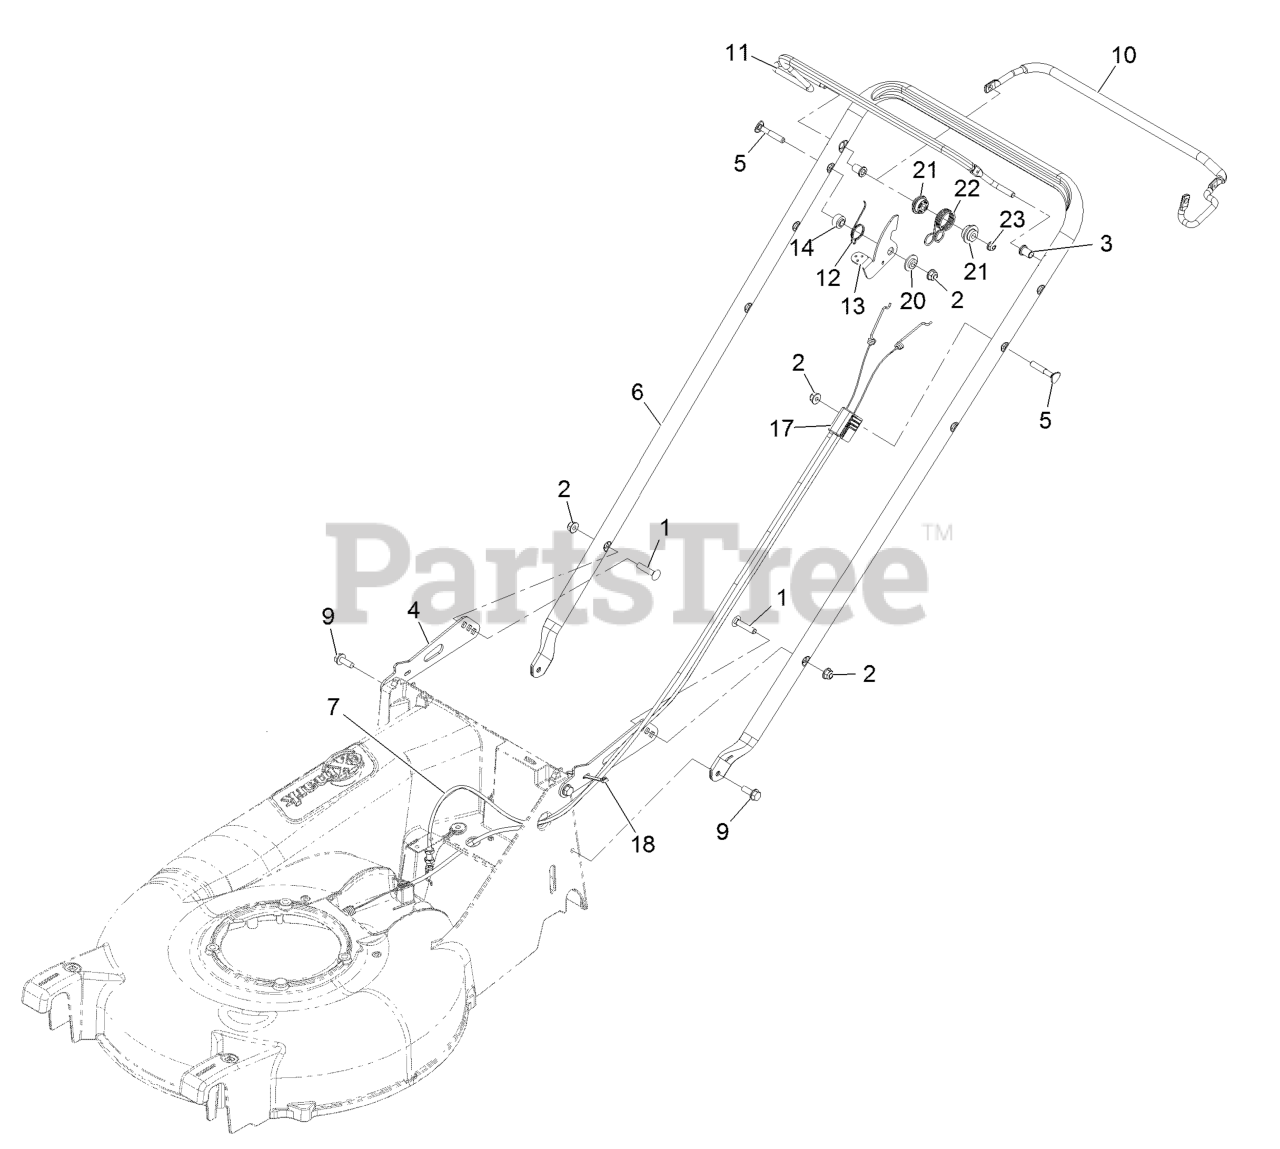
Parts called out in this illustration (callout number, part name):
1	BOLT-CARR
2	NUT-HF, NI
3	BUSHING-HANDLEBAR
4	BRACKET,HANDLEBAR
6	HANDLEBAR-P21
9	SCREW-TAPTITE
10	BAIL-DRIVE COATED
12	SPRING-LEVER, BBC
13	LEVER-BBC
14	BUSHING-STEPPED
17	CABLE-BBC
18	TIE-CABLE
20	WASHER-STEPPED
21	BUSHING-SPRING, PIVOT
22	SPRING,BBC RETURN
